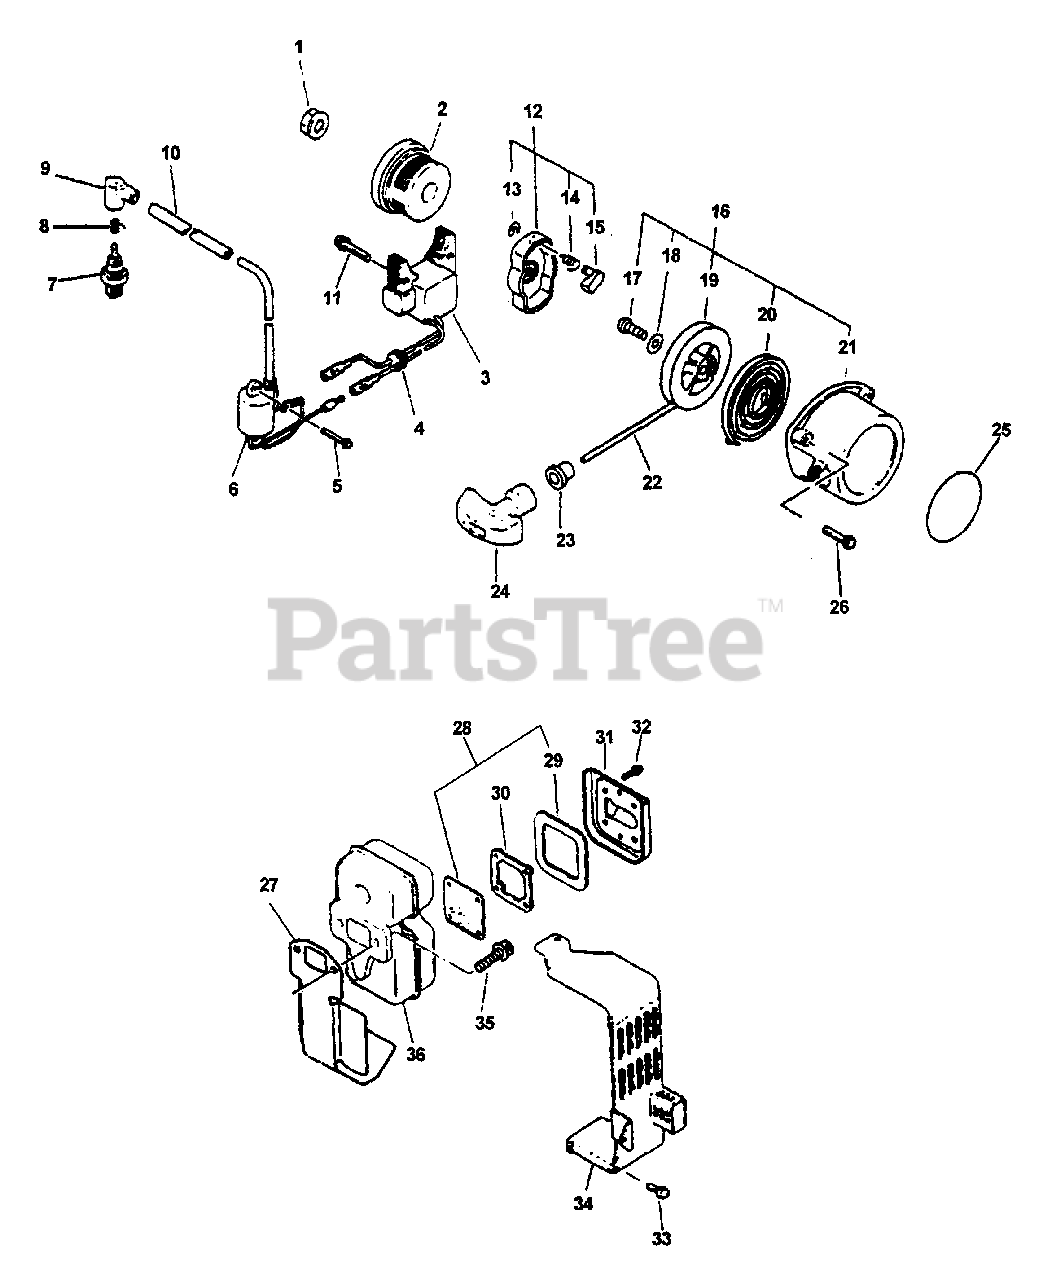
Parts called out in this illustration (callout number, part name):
1	NUT - 10 -- FLANGE
2	FLYWHEEL
3	COIL, IGNITION
5	SCREW - 4X25
6	COIL, IGNITION
7	SPARK PLUG -- BM-6A
8	TERMINAL, SPARK PLUG CAP
9	CAP, SPARK PLUG
11	SCREW - 5X25
12	STARTER PAWL ASSY
13	RING, RETAINING - 4
14	SPRING, RETURN
15	PAWL, STARTER
16	STARTER ASSY
19	REEL, ROPE
20	SPRING, REWIND
21	CASE, STARTER
22	ROPE, STARTER - 4X950
23	GUIDE, ROPE
24	GRIP, STARTER
25	LABEL - ECHO
26	SCREW - 5X16
27	GASKET, EXHAUST
28	SCREEN, SPARK ARRESTOR
29	GASKET, EXHAUST
30	RETAINER, SCREEN
31	GUIDE, EXHAUST
32	SCREW - 4X14
33	SCREW - 5X14
34	COVER, EXHAUST
35	SCREW - 6X20
